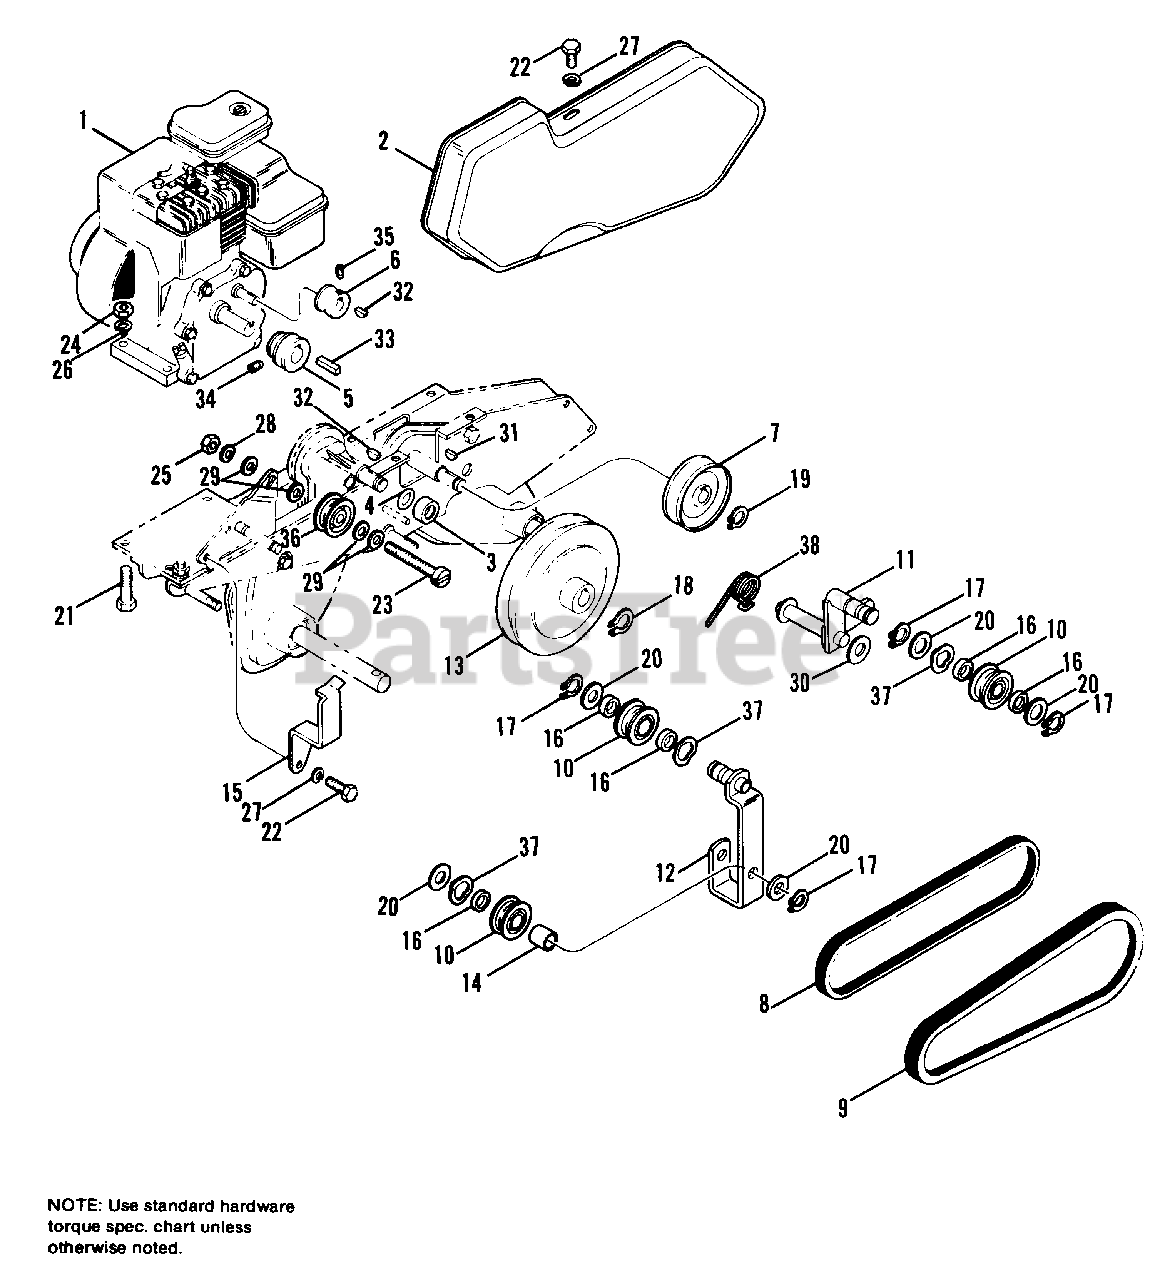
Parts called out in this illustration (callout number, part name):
1	ENGINE-5 H.P. B & S Model 130292 (See engine ID plate for type)
2	BELT GUARD
5	ENGINE PULLEY
6	CAMSHAFT PULLEY
7	PULLEY ASSEMBLY-Tines
8	TRACTION DRIVE BELT
9	TINE DRIVE BELT
10	IDLER PULLEY ASSEMBLY
11	ROCKER ASSEMBLY
12	IDLER ARM ASSEMBLY
13	PULLEY ASSEMBLY-Traction
14	SPACER-Idler
15	BELT GUIDE
17	RETAINING RING
18	RETAINING RING
19	RETAINING RING
21	CAP SCREW, Hex Hd. 5/16-18 x 1-1/2" Plated
22	CAP SCREW, Hex Hd. 1/4-20 x 1/2" Plated
23	MACHINE SCREW, Slotted Rd. Hd. 3/8-16 x 1-3/4" Plated
24	NUT, Hex 5/16-18 Plated
25	NUT, Hex 3/8-16
26	WASHER, Spring Lock 5/16 Plated
27	WASHER, Spring Lock 1/4 Plated
28	WASHER, Spring Lock 3/8
29	WASHER, Flat SAE 3/8 Plated
30	WASHER, Flat SAE 1/2 Plated
31	KEY, Woodruff 3/16 x 3/4"
32	KEY, Woodruff 1/8 x 5/8
33	KEY, Square 3/16 x 3/16 x 1"
34	SETSCREW, Hex Socket Hd. Cup Pt. 5/16-18 x 5/16" Heat Treated
35	SETSCREW, Hex Socket Hd. Cup Pt. 1/4-20 x 1/4" Heat Treated
36	PULLEY-Idler
37	WAVE WASHER
38	SPRING-Torsion
